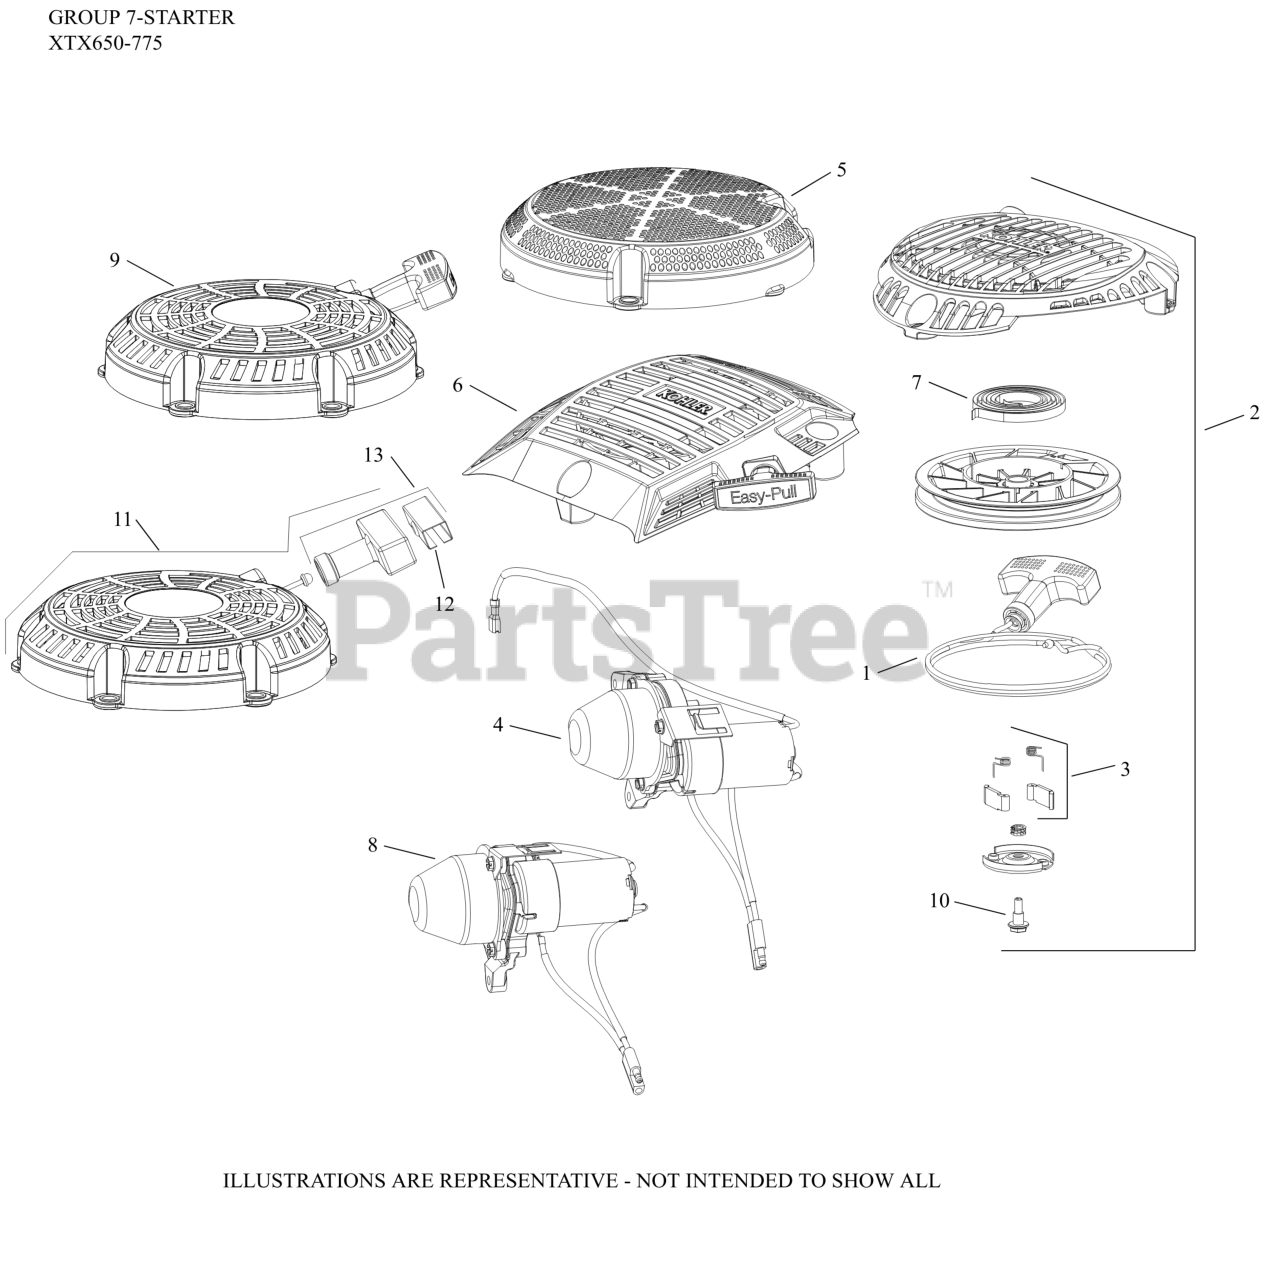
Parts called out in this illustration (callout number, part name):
1	KIT, STARTER ROPE W/HANDLE
2	STARTER ASSEMBLY, RETRACTABLE
3	KIT, PAWL REPAIR
5	INSERT, DEBRIS SCREEN
